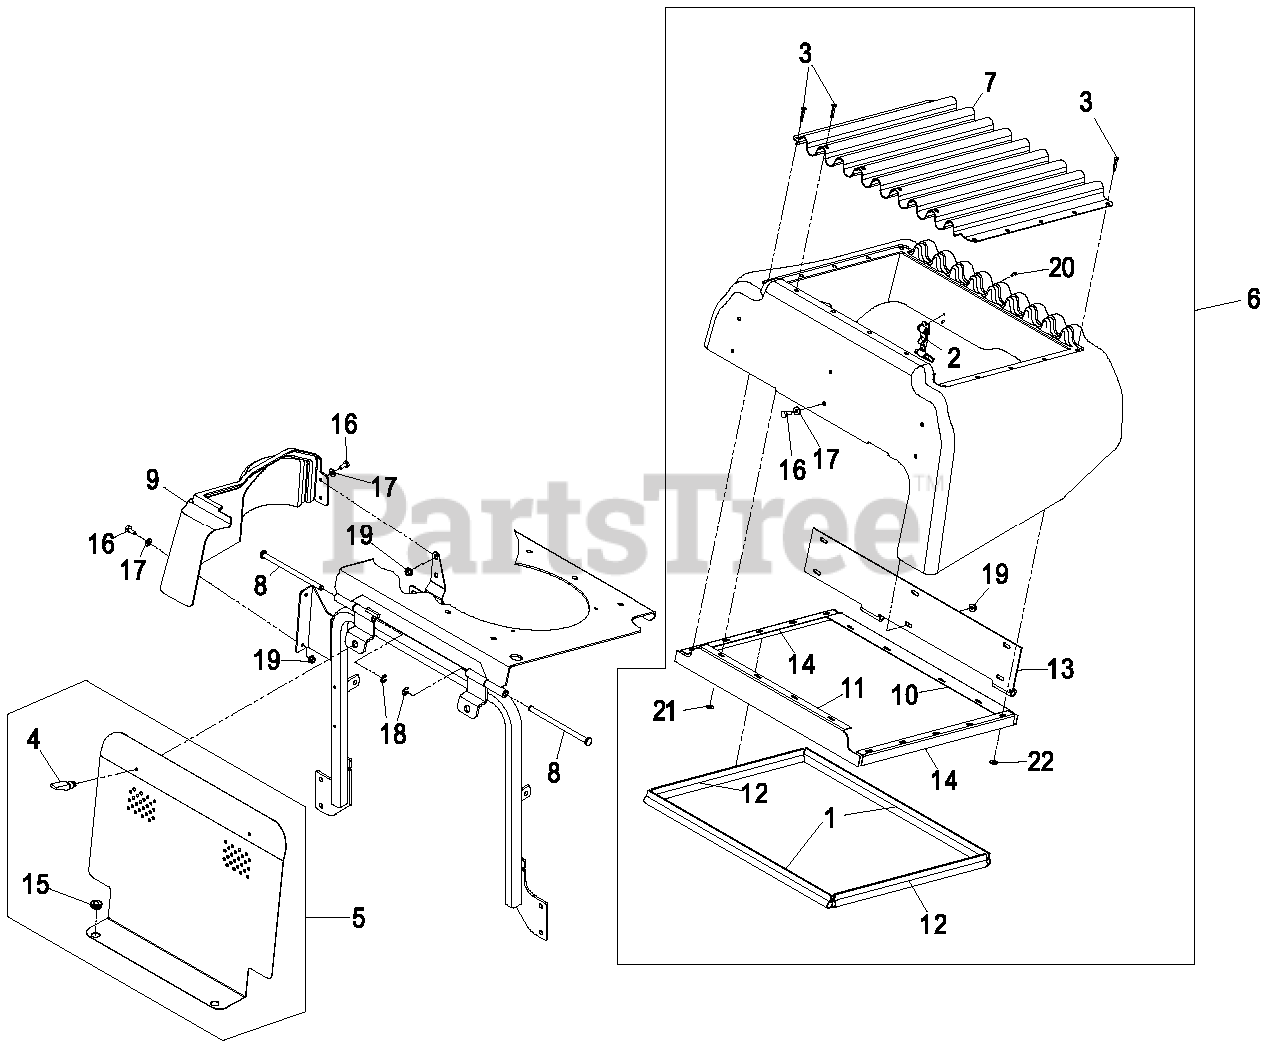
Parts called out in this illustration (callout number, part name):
1	SEAL-TRIM
2	LATCH-RUBBER
4	LATCH-SWELL
7	SCREEN, RADIATOR
9	PANEL, SIDE
10	MOUNT,SEAL REAR
11	MOUNT,SEAL FRONT
12	SEAL,TRIM 17.1
13	WLD, HINGE
14	MOUNT,SEAL SIDE
15	GROMMET
16	SCREW-HH
17	WASHER-FLAT
21	WASHER-SPRING
22	WASHER-FLAT
